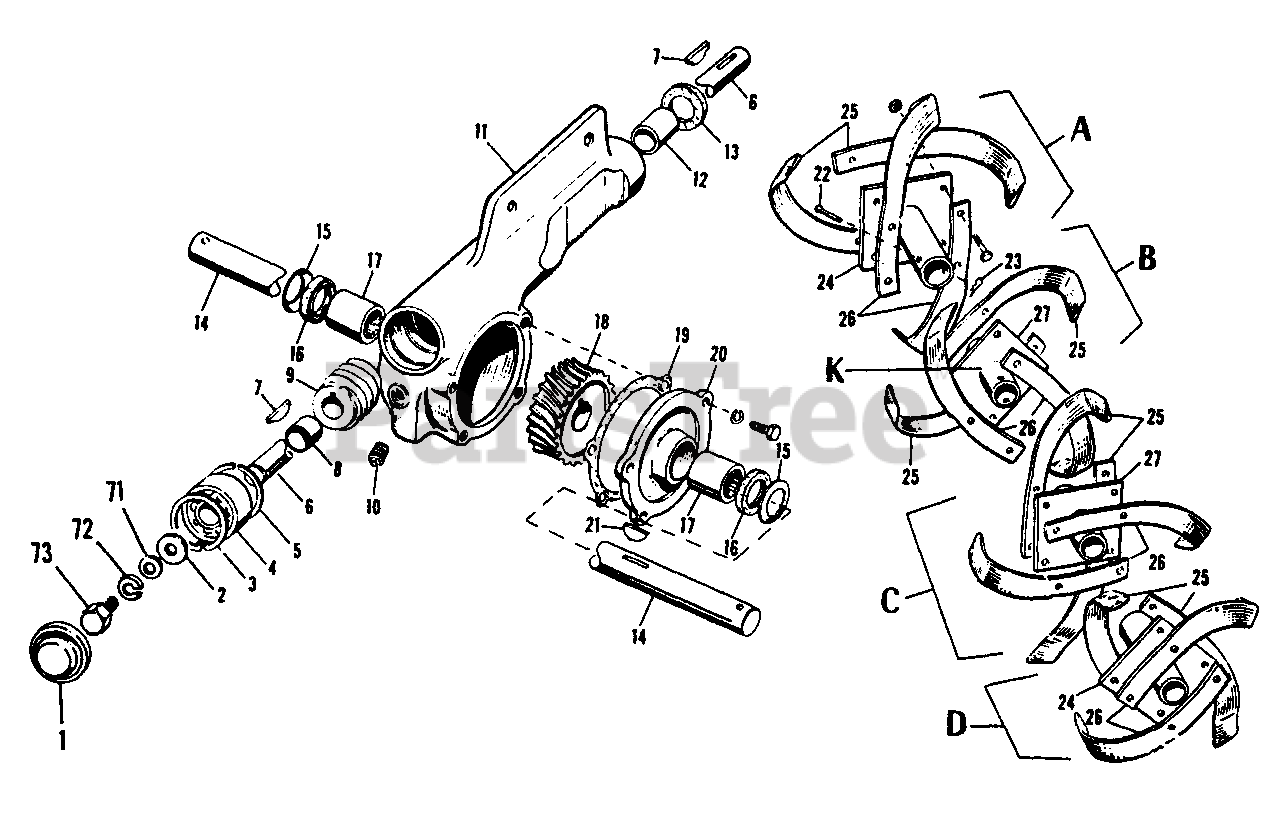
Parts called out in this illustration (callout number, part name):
3	Retaining Ring
4	Ball Bearing
5	Snap Ring
6	Worm Shaft
7	Key, Hi-Pro #706
10	Pipe Plug, 3/8" Std.
11	Worm Drive Housing
14	Worm Gear Shaft
17	Needle Bearing
21	Key, Woodruff, 1/4" x 3/4"
22	Pin
23	Spring Clip
24	Plate Assembly, Tine Outer
25	Blade, L. H. Tine
26	Blade, R.H. Tine
27	Plate Assembly, Tine Inner
71	Washer, Plain, 5/16"
72	Lock Washer, 3/8"
73	Capscrew, Hex Head, 3/8-16 x 3/4"
